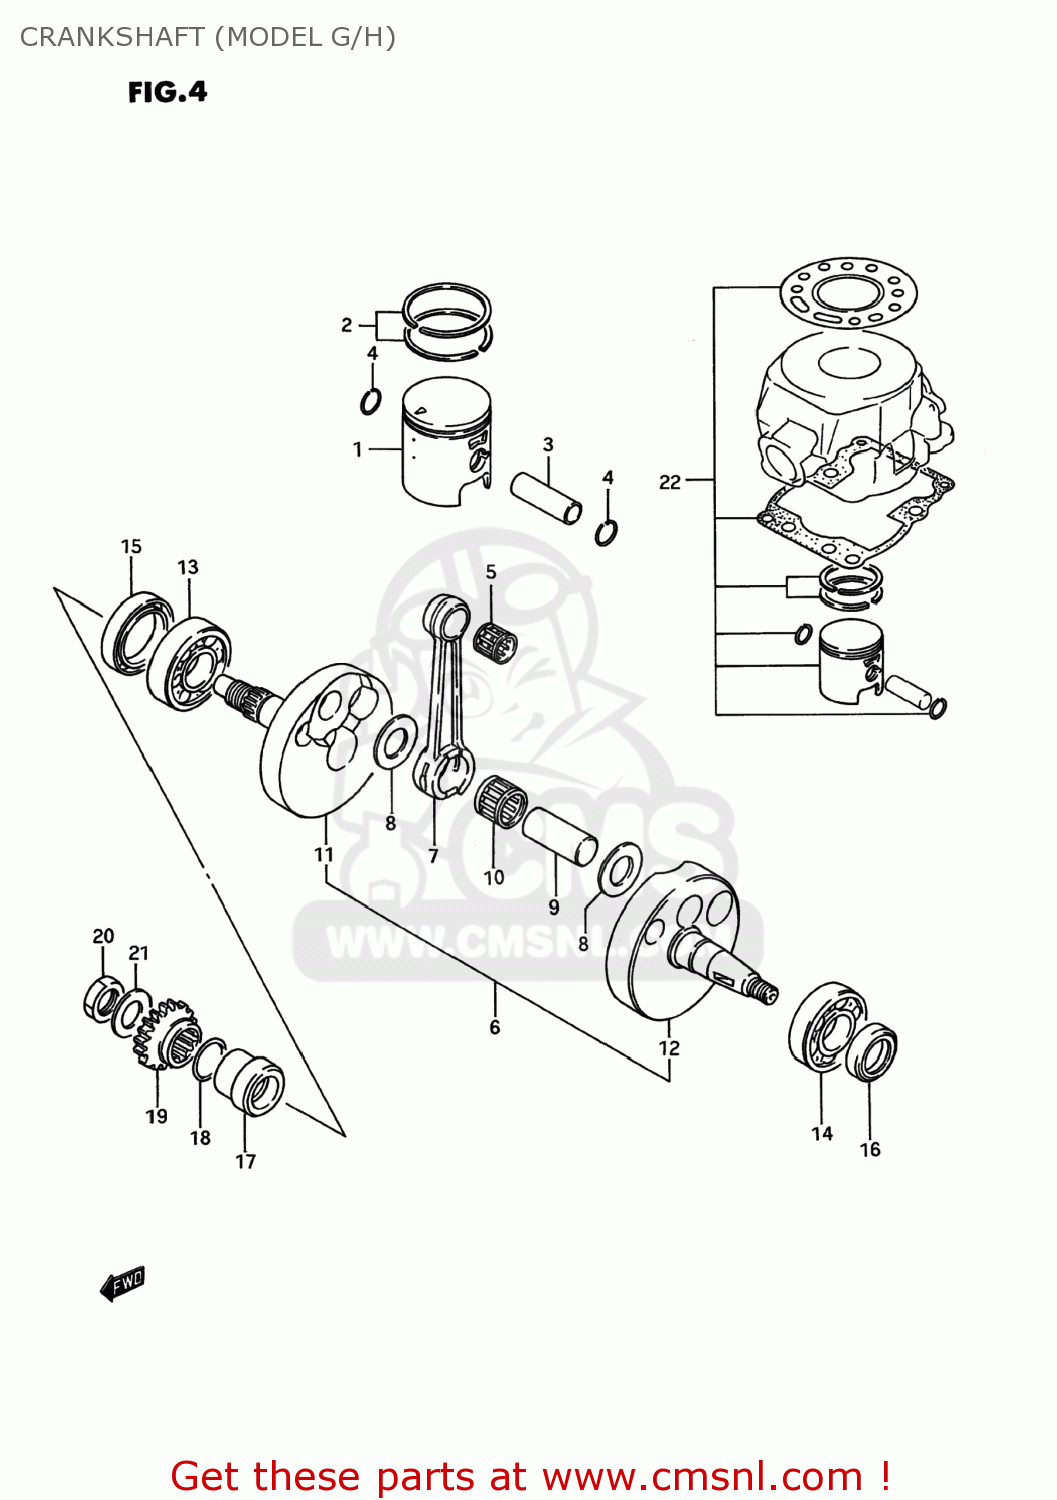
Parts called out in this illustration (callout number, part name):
1	PISTON
2	RING SET,PISTON(STD)
3	PIN,PISTON
4	RING,SNAP 14MM
5	BEARING(14X18X16)
6	CRANKSHAFT ASSY
7	CONNECTING ROD
8	WASHER(18X32X1)
9	PIN,CRANK
10	BEARING
11	CRANKSHAFT,RIGHT
12	CRANKSHAFT,LEFT
13	BEARING(20X52X15)
14	BEARING(20X47X14)
15	SEAL,OIL(32X44X8)
16	SEAL,OIL(18X30X8)
17	SPACER,PRIMARY DRIVE GEAR
18	O RING(D:2.4,ID:19.8)
19	GEAR,PRIMARY DRIVE
20	NUT
21	WASHER
22	PISTON SET (STD)
